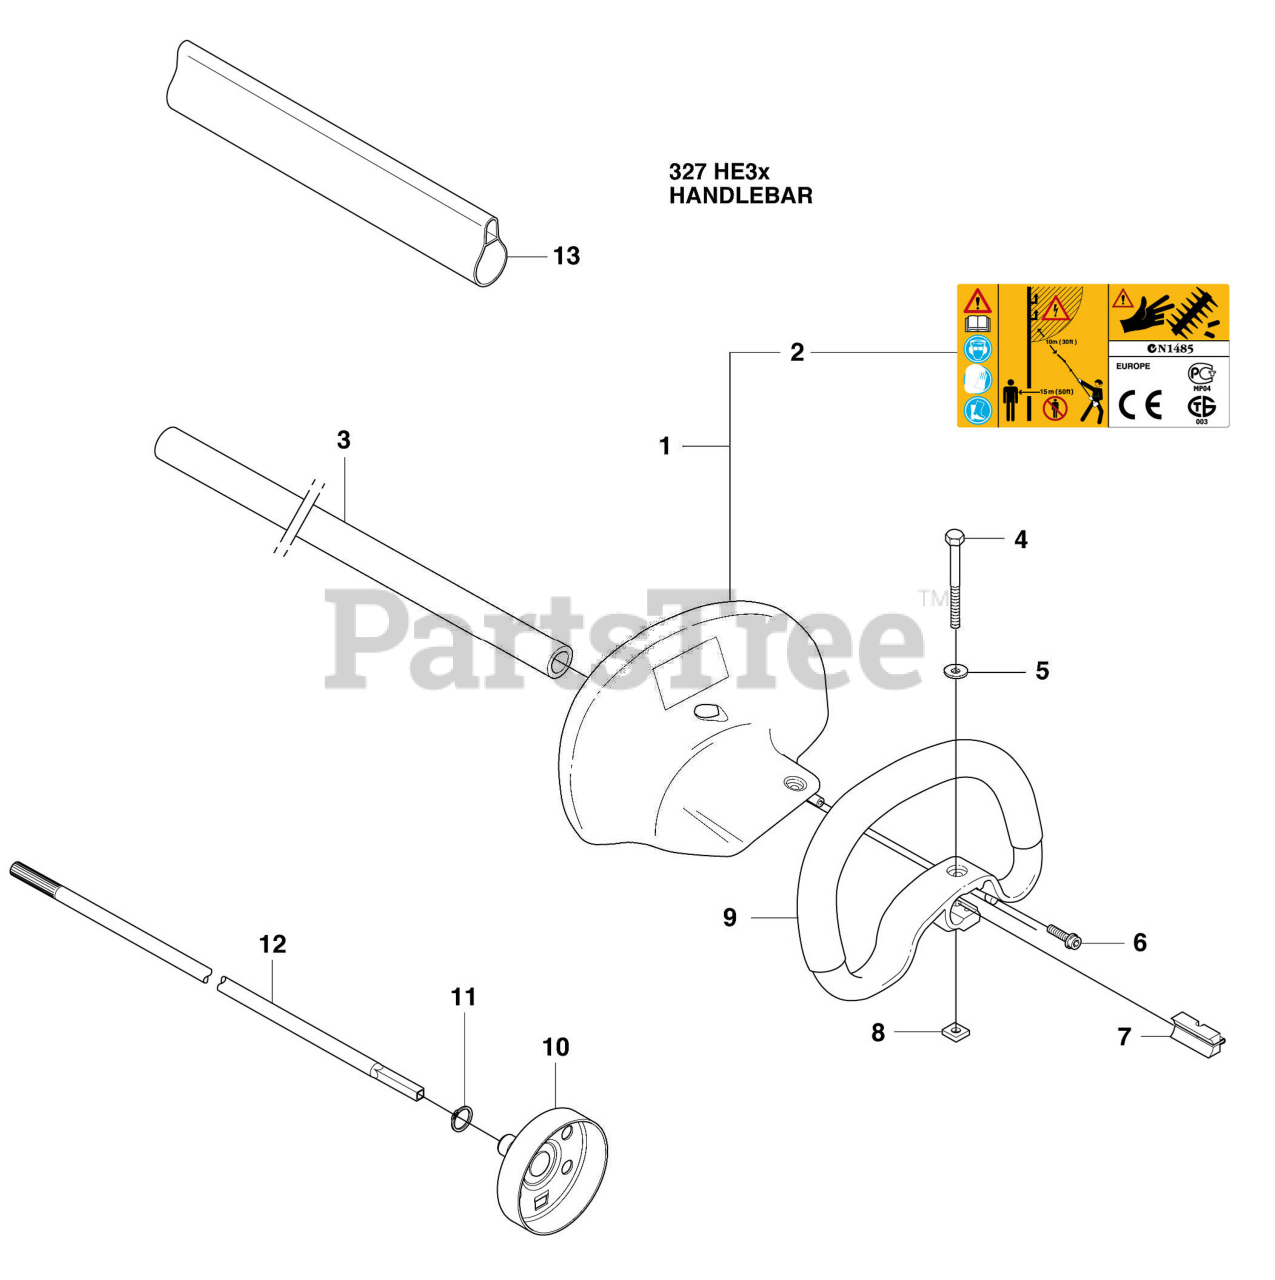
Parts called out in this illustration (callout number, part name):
1	RP HAND GUARD
2	Warning Label
5	Washer, M6
7	Spacer, Plastic
9	Handle
10	Clutch Drum
12	DRIVE AXLE HE3
13	PROTECTOR
